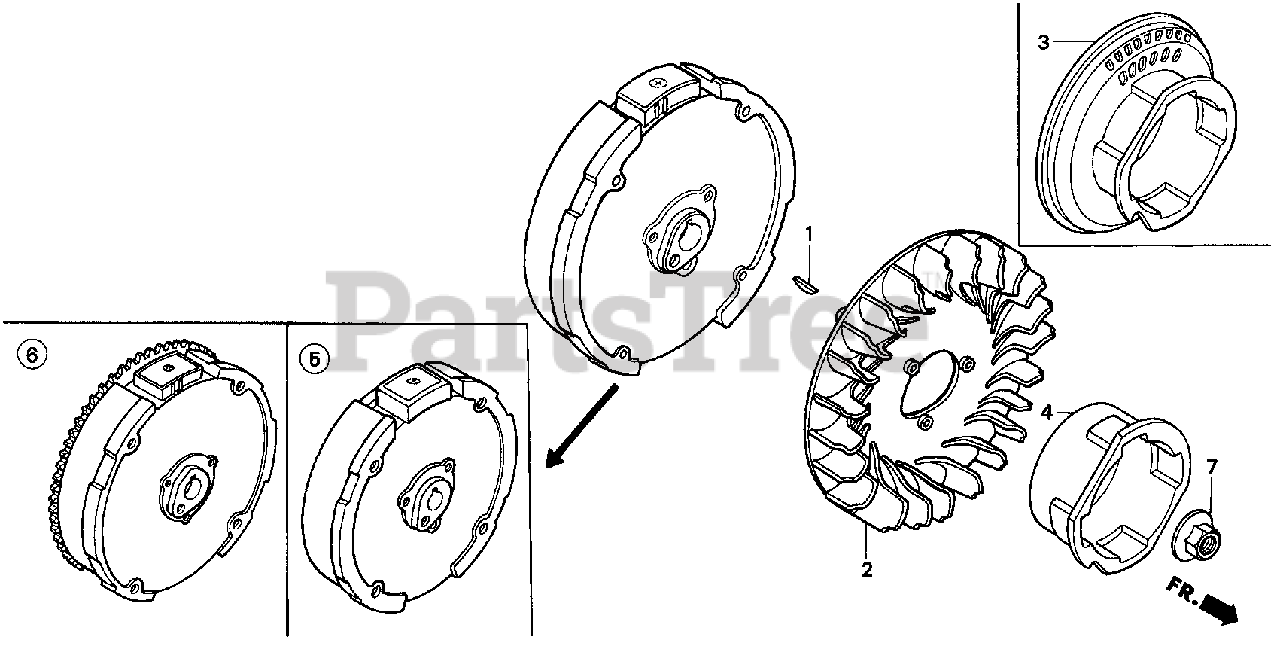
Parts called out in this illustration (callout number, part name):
1	KEY, SPECIAL WOODRUFF (25X18)
2	FAN, COOLING
3	PULLEY, STARTER
5	FLYWHEEL (STD)
7	NUT, SPECIAL (14MM)
